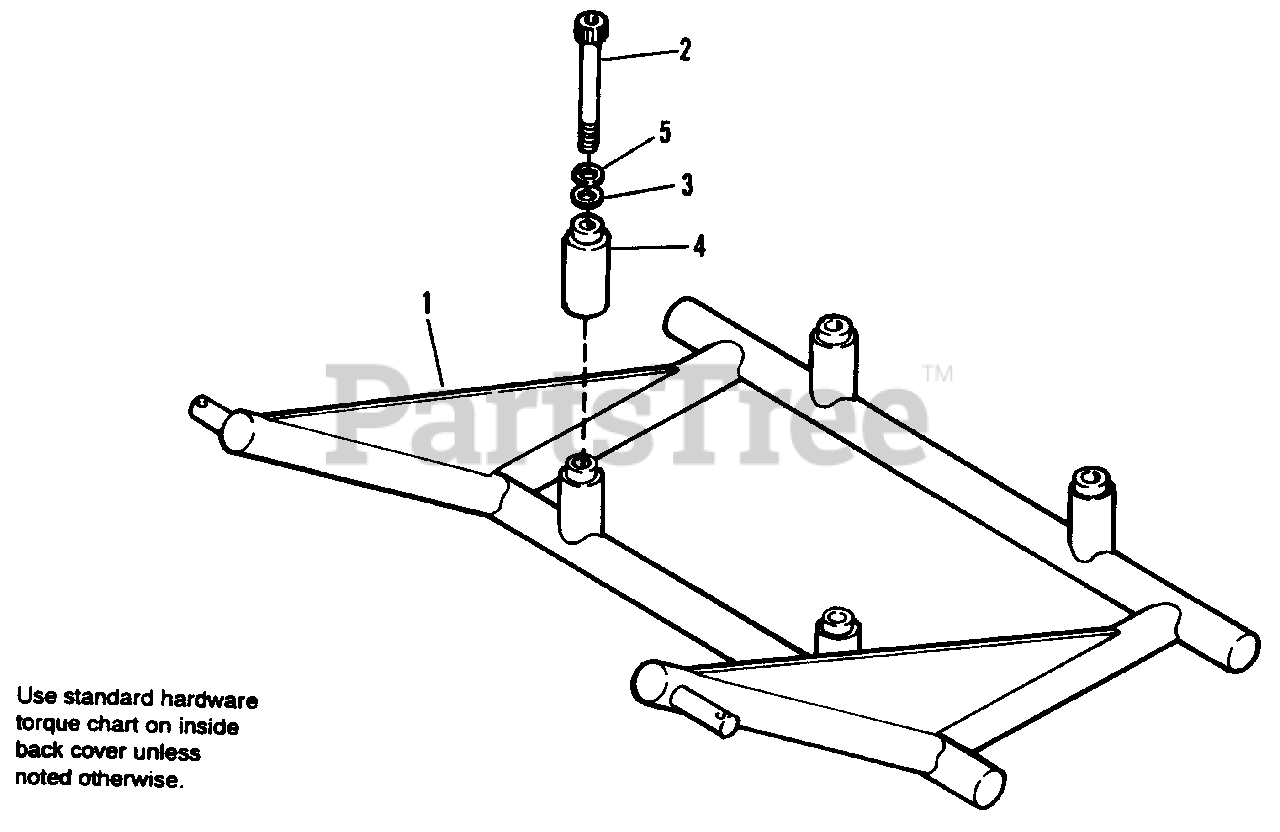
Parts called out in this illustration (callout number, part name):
1	SKID, 20 HP
1	SKID, 23 HP
2	CAPSCREW, Hex Hd., 1/2-13 x 8 (20 HP)
3	WASHER, 1/2"
4	SKID, Leg Spacer, 6" (20 HP)
4	SKID, Leg Spacer, 4" (23 HP)
5	LOCKWASHER, 1/2"
